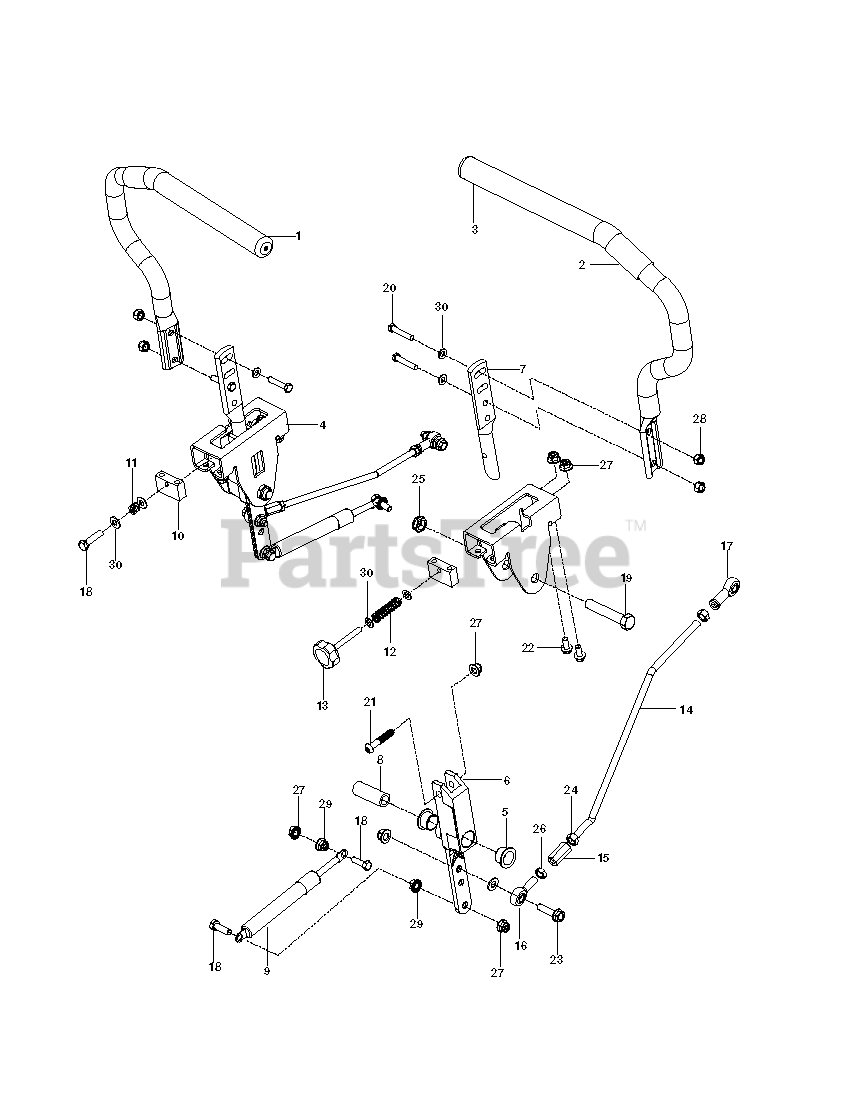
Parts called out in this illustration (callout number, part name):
1	LEVER.DRIVE.W/GRIP.RIGHT
2	LEVER.DRIVE.W/GRIP.LEFT
3	GRIP - DRIVE LEVER 12"
4	BRACKET, CONTROL
5	BEARING, FLANGE
6	LEVER CONTROL PIVOT
7	LEVER.HANDLE MOUNT
8	SPACER, PIVOT CONTROL
10	BLOCK.TRACKING
12	SPRING COMPRESSION 2.0
13	KNOB
14	ROD, CONTROL
15	ROD END COUPLER
16	RP.ROD.END.LH
17	RH ROD END
18	HCS 5/16C X 1 1/4
19	HCS 1/2C X 2 3/4
20	CAPSCREW 5/16 X 1/1/2 HEX HEAD
21	SCREW 5/16-18 X 1 3/4 BTN-HD
22	HHFS 5/16-18 X 3/4
23	HHFS 5/16-18 X 1.25 TPBLT GD 5
25	NUT 1/2-13 HEX JM NYL
26	NUT 5/16F LEFTHAND
27	5/16-18 NYLOC FLANGE NUT
28	NUT 5/16 NYLOC
29	NUT 5/16C WHIZ
30	FLAT WASHER 5/16 SAE
